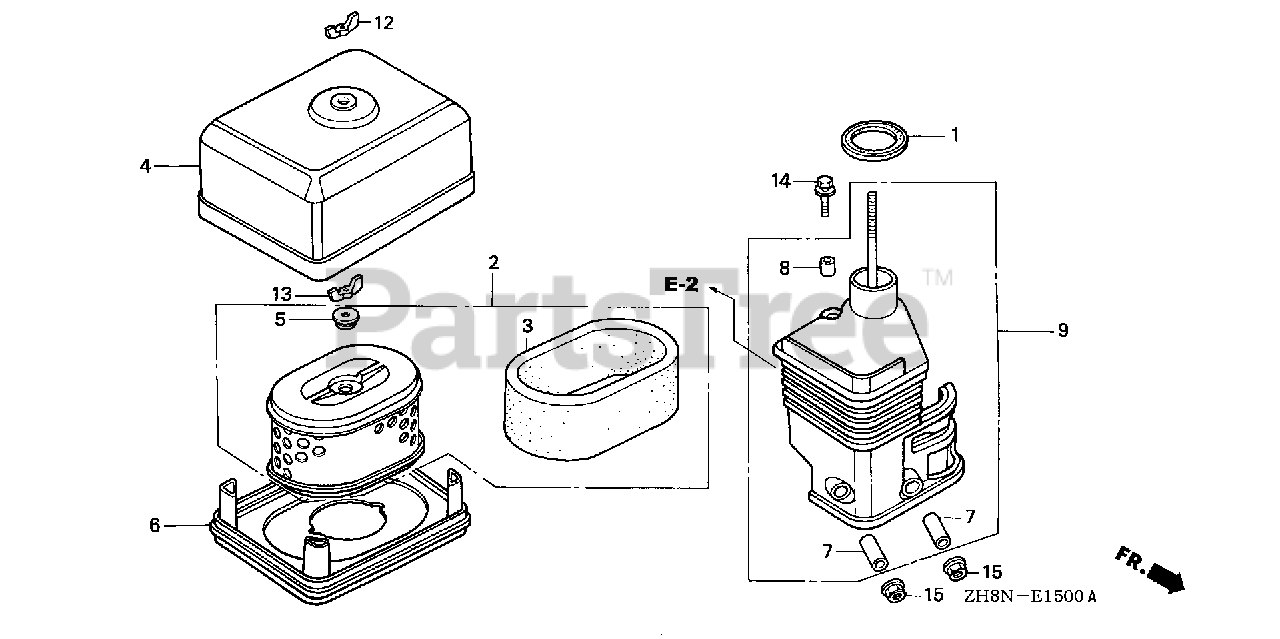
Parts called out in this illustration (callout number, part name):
1	GASKET, ELBOW
2	ELEMENT, AIR CLEANER (DUAL)
3	FILTER (OUTER)
4	COVER, AIR CLEANER (DUAL)
5	GROMMET, AIR CLEANER
7	COLLAR, AIR CLEANER
8	COLLAR B, AIR CLEANER
9	ELBOW, AIR CLEANER
12	WINGNUT, TOOL BOX SETTING
13	WINGNUT, TOOL BOX SETTING
14	BOLT, FLANGE (6X20)
15	NUT, FLANGE (6MM)
